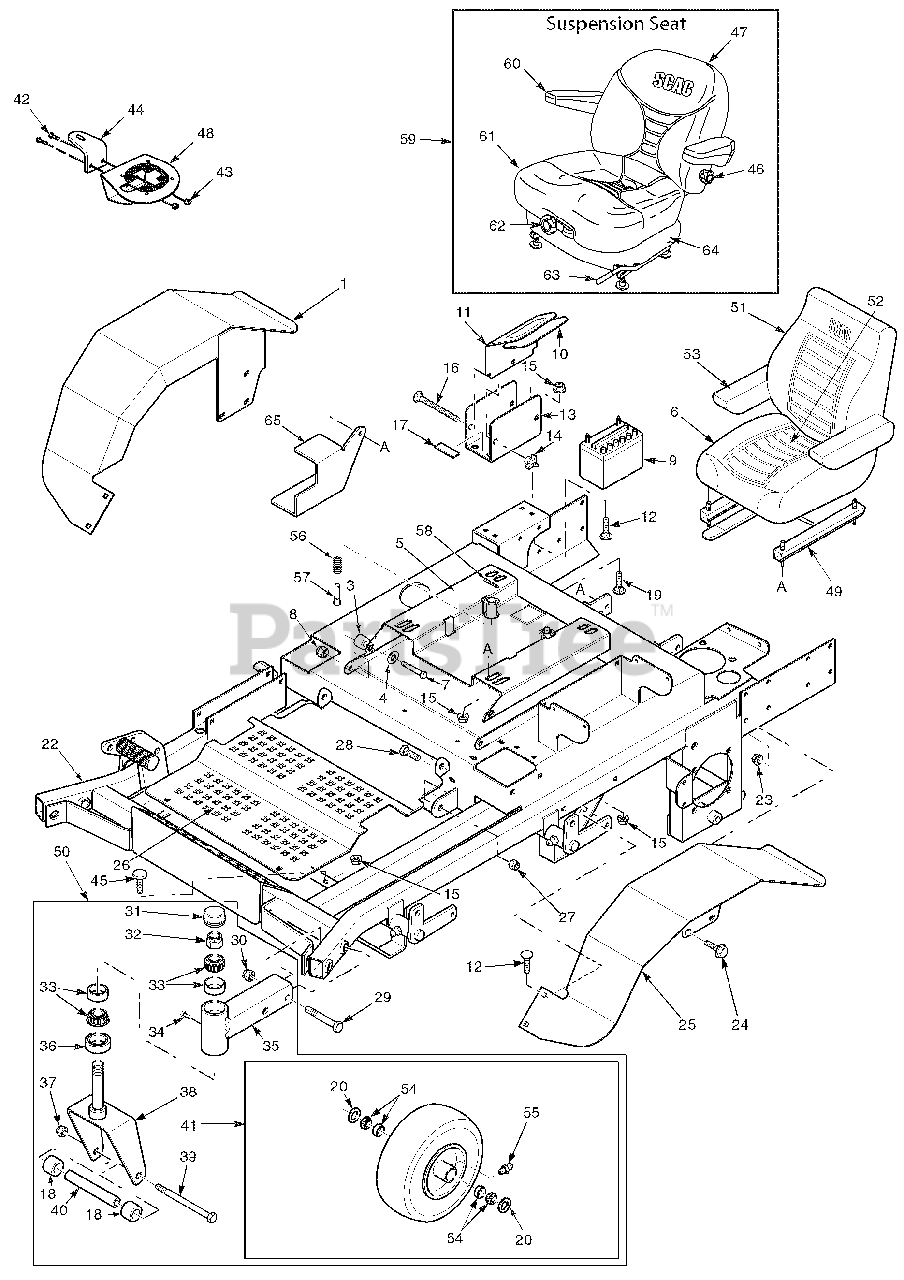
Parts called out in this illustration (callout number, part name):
1	Fender Weldment, RH
2	Bolt, Hex Head, 5/16-18 x 1, Zinc
3	Spacer
4	Flatwasher, 3/8-.391 x .938 x .105
5	Seat Plate Weldment
6	Seat Assembly w/armrest and seat belt
7	Bolt, Hex Head 3/8-16 x 2.0"
8	Nut, Elastic Stop 3/8-16
9	Battery
10	Pad, Battery Cover
11	Cover, Battery
12	Bolt, Carriage 5/16-18 x 3/4"
13	Plate, Battery Box
14	Wing Nut, 1/4-20 x 3/4"
15	Nut, Hex Serrated Flange 5/16-18
16	Bolt, Carriage 1/4-20 x 6"
17	Rubber Pad
18	Spacer, Caster Wheel
19	Bolt, Carriage 5/16-18 x 1"
21	Lock Nut, 3/8-16, Elast. Stop
22	Main Frame
23	Nut, Hex Serrated Flange 3/8-16
24	Screw, Hex Serrated Flange 3/8-16 x 1"
25	Fender Weldment, LH
26	Foot Plate
27	Nut, Hex Elastic Stop 3/8-16
28	Bolt, Hex Head 3/8-16 x 1"
29	Bolt, Hex Head 5/8-11 x 4"
30	Nut, Hex Elastic Stop 5/8-11
31	Cap, Grease
32	Nut, Hex Elastic Stop 1.0-14
33	Bearing W/Race
34	Plug, 1/4-28 THD Form
35	Extention Weldment, Caster 61V
36	Seal, 2.00 OD. x 1.625 Bore
37	Nut, Hex Elastic Stop 1/2-13
38	Yoke Weldment, Caster
39	Bolt, Hex Head 1/2-13 x 9-1/2"
40	Sleeve, Caster Wheel
41	Wheel Assy, 61V, 72A
42	Bolt, Hex Head 1/4-20 x 3/4"
43	Bolt, Hex Head 1/4-20 x 3/4"
44	Mounting Bracket, STT Cup Holder
45	Lumbar Kit
46	Cable, Seat Stop
47	Back Cushion Kit
48	Cup Holder Assembly
49	Seat Adjustment, Track Set
50	Caster Wheel Assy 61V
51	Back Cushion Cover
52	Seat Cushion Cover
53	Arm Rest, Right Hand
54	Bearing w/ Race
55	Grease Fitting
56	Spring, Seat
57	Pin Retainer, Spring
58	Roll Pin, Spring 5/32 x 3/4"
59	Suspension Seat Assembly w/seat belt
60	Armrest Only
61	Seat Cushion Kit Seat Drain Kit
62	Weight Adjustment Kit
63	Seat Adjustment, Track Set
64	Shock Absorber Kit
65	Guard, Fuel Line
